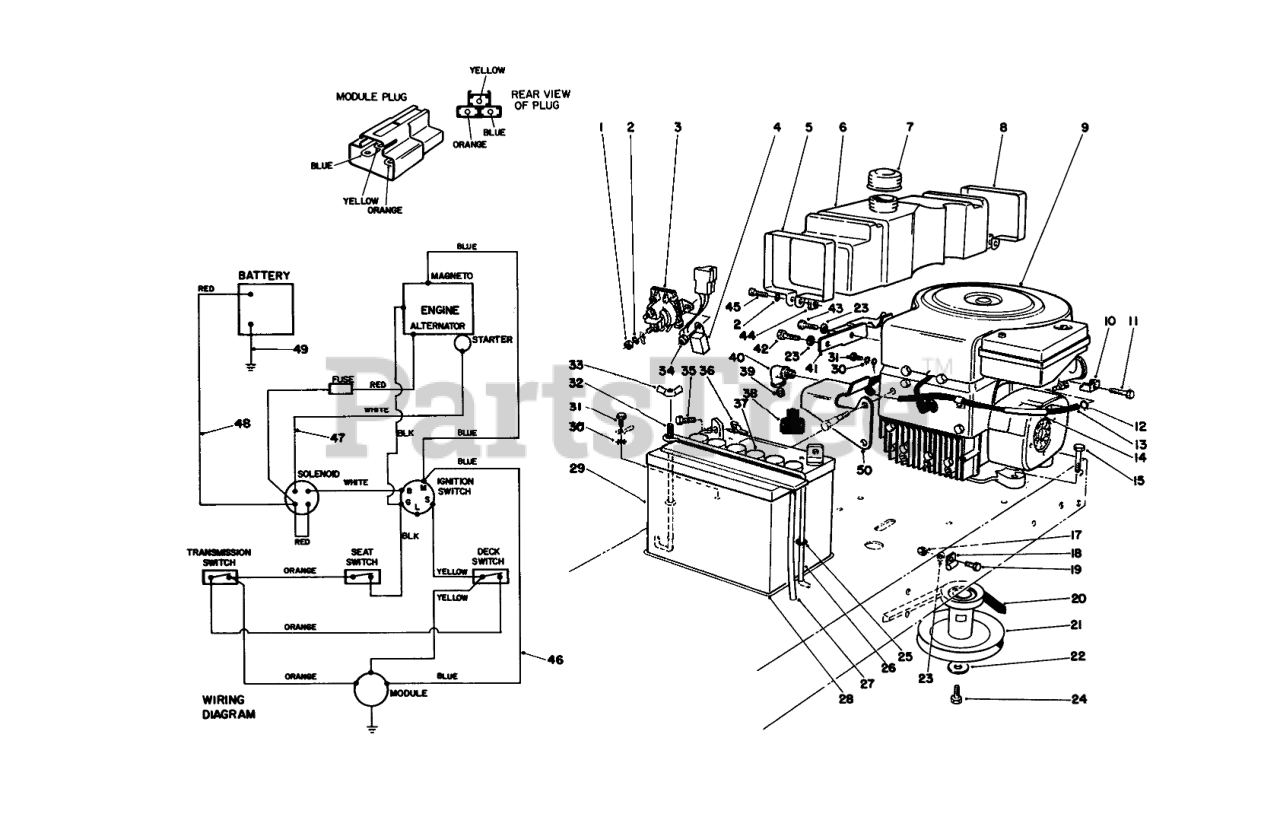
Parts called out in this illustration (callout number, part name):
1	NUT-JAM
2	WASHER-LOCK
3	SOLENOID
4	Module Interlock
5	Retainer-Front
6	TANK-5 QT GAS
7	GAS CAP ASM
8	Retainer-Rear
10	CLAMP-CASING
11	SCREW W ENGINE
12	CLAMP-HOSE
13	HOSE-FUEL
14	SUPPORT-FUEL LINE
15	SCREW-HH
17	NUT-LOCK, NI
18	CLAMP
19	SCREW-HH
20	V-BELT, TRACTION
21	ENGINE PULLEY ASM
22	WASHER-FLAT
23	WASHER-PLAIN
24	SCREW-HH
25	O-RING
26	Hold Down-Battery
27	TUBE-BATT DRAIN/80-2600
28	PAD-SKID, ANTI
29	Battery
30	WASHER-LOCK, INTERNAL
31	SCREW-HWHTF
32	POST-BATTERY
33	NUT-WING
34	NUT-LOCK, NI
35	SCREW-HH
36	NUT-WING
37	CAP-BATTERY
38	BOOT-TERMINAL
39	3/8 PIPE PLUG
40	ELBOW-STREET, 90 DEG
41	REAR TANK MTG BRKT B
42	SCREW-HH
43	SCREW-HH
44	NUT-SQUARE
45	SCREW-HSH
46	WIRING HARNESS
47	WIRE HARNESS
48	WIRE ASM
49	WIRE ASM(BATT/GRD.
50	FRT TANK MTG BRKT B
